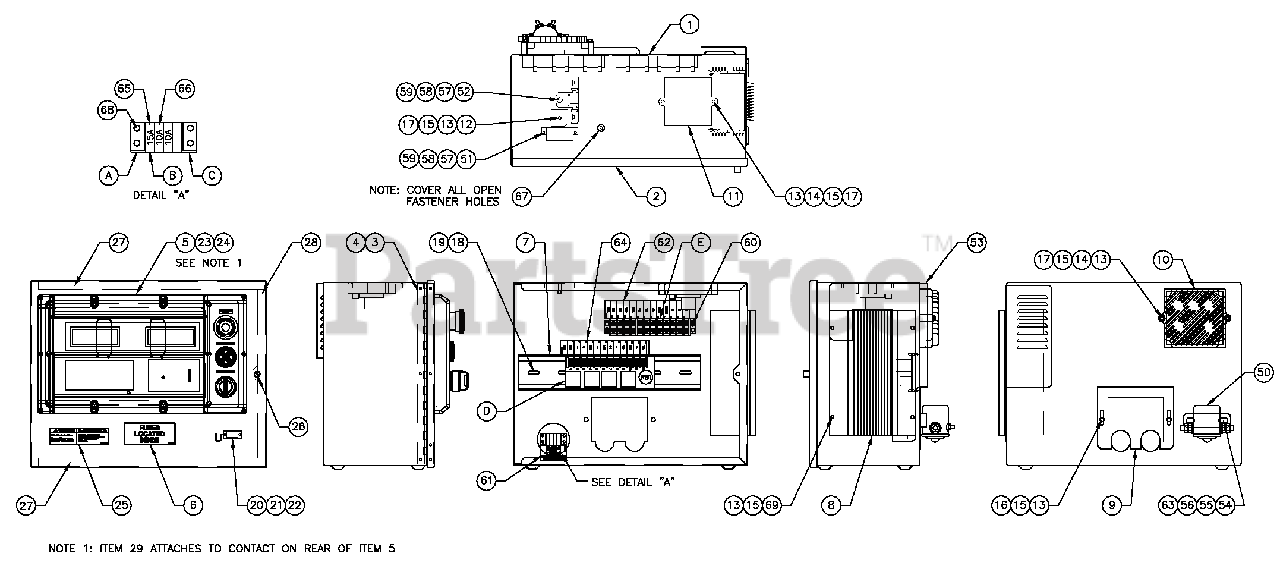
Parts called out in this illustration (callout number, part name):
1	ENCLH/G CONTROL PANEL
2	COVER CONTROL PANEL
3	HINGECONTINUOUSH PANEL
4	RIVET POP .125 X .275 SS
5	ASSYPROGRAMMEDH-100
6	DECAL FUSES LOCATED INSIDE
7	RAILSNAPTRACK PCB HOLDER BULK
8	ASSY PCB 10A ULBATT CHRGR12V
9	PLATE HARNESS CLAMP
10	ASSY PCB PWR AVR W/AMP HEADER
11	ASSY PCB BOSCH GOV DRIVER
12	DIO BRIDGE25A 600V
13	WASHER LOCK M5
14	SCREW PPHM M5-0.8X 30SS
15	WASHER FLAT M5
16	SCREW HHPM M5-0.8 X 12
17	NUT HEXM5-0.8 G8 YEL CHR
18	WASHER FLAT M4
19	SCREW PHTT M4-0.7X 10ZYC
20	CONN DUST CAP W/CHAIN DB9
21	WASHER FLAT M3.5
22	SCREW PHTT M3.5-0.6 X 10
23	SCREW PPHM M4-0.7X 8 BLXOX
24	WASHER LOCK #8-M4
25	DECAL WRNB ATT CHRG12/24V BI
26	M5-0.8 CAPTIVE PANEL KNLD HD
27	SEAL COVER 3.18 X 12.7X 382
28	SEAL COVER 3.18 X 12.7X 283
29	HARNESS H-PNL INTEGRATED SW (N(
50	RELAY CONTACTOR 12VDC
53	COVER CONTROL PANEL SIDE
54	SCREW HHC 1/4-20X 3/4G5
55	WASHER FLAT M6-1/4
56	WASHER LOCK M6-1/4
57	WASHER LOCK M3
58	NUT HEXM3-0.5 G8 YEL CHR
59	WASHER FLAT M3
60	SCREW PHTT#6-32X 5/8ZYC
61	DECAL CPL CONTROL PANEL FUSES
62	DECAL CPL 5.4/6.8LTB3
63	NUT HEX 1/4-20 STEEL
64	DECAL CPL 5.4/6.8L RELAY BOARD
65	FUSE ATO TYPE 15 AMP (BLUE)
66	FUSE ATO TYPE 10 AMP (RED)
67	SEAL WEATHER.45"DIA
68	SCREW PHTT#6-32X 3/8ZYC
69	SCREW PHTT M5-0.8X 16ZYC
A	ADPTR RH SIDE WICKMANN 178.6191
B	HOLDERFUSE WICKMANN 178.6150
C	ADPTR LH SIDEWICKMANN 178.6192
D	ASSY PCB G-PANEL RELAY 12VDC
E	BLOCK TERM 20A 12X 6 X1100V
